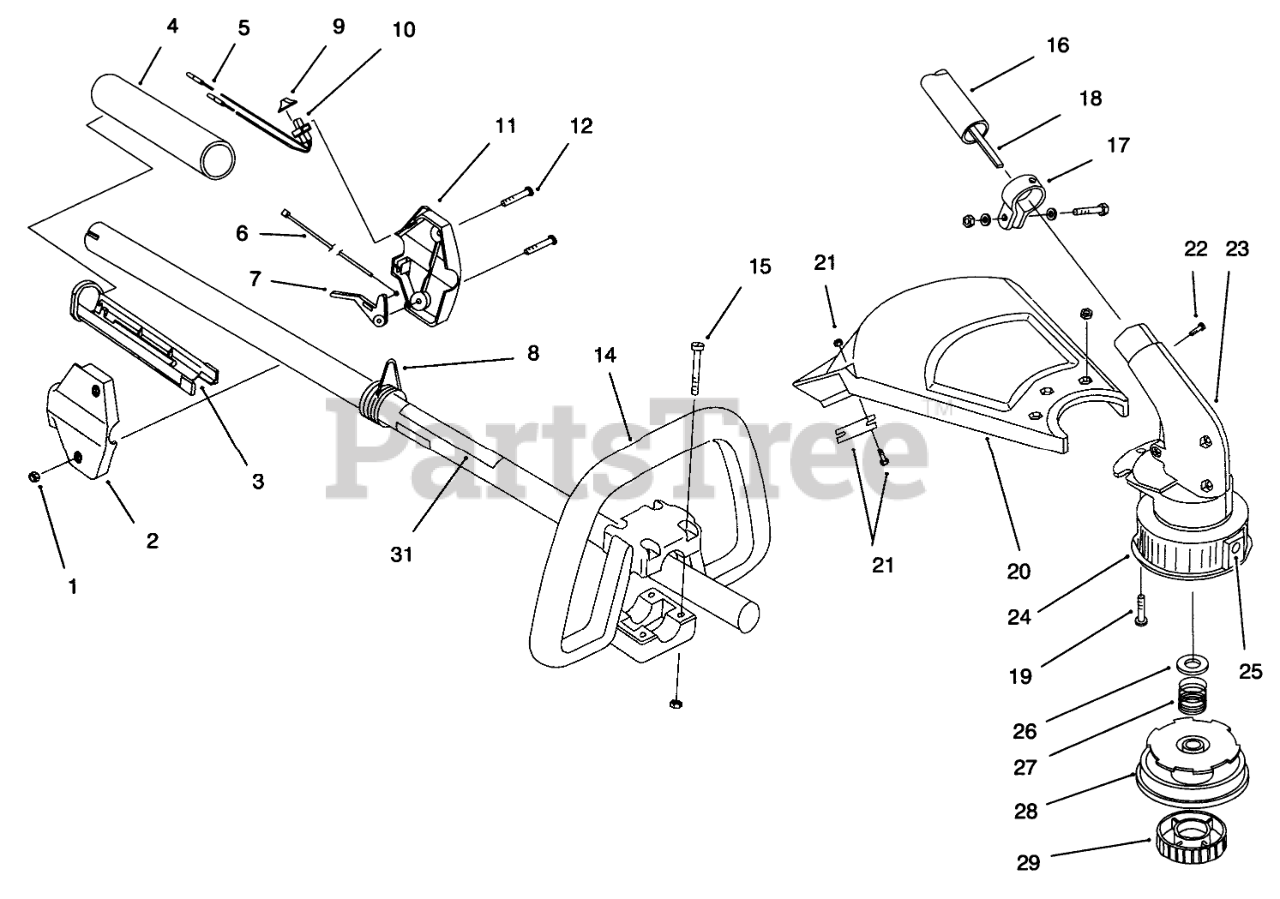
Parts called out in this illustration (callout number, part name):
1	NUT-LOCK, NI
2	RH HOUSING
3	TROUGH 1"
4	GRIP - RUBBER
5	LEAD WIRE ASM
6	THROTTLE CABLE
7	THROTTLE LEVER
8	Clip-Shoulder Strap
9	SWITCH COVER
10	SWITCH
11	LH HOUSING
14	HANDLE W/HARDWARE
15	HARDWARE - HANDLE
16	ASM - DRIVE SHAFT HSG
17	CLAMP ASM - UPPER
18	Drive Shaft
19	ASM - GUARD MTG SCREW
20	Guard and Blade Asm.
21	BLADE ASM
22	ANTI-ROTATION SCREW
23	ASM - GEAR BOX
24	OUTER SPOOL EYELET ASM
25	EYELET
26	RETAINER WASHER(SET OF 10)
27	SPRING
28	REEL - INNER
29	Assy.-Bump Head
31	Decal-Safety Symbol
